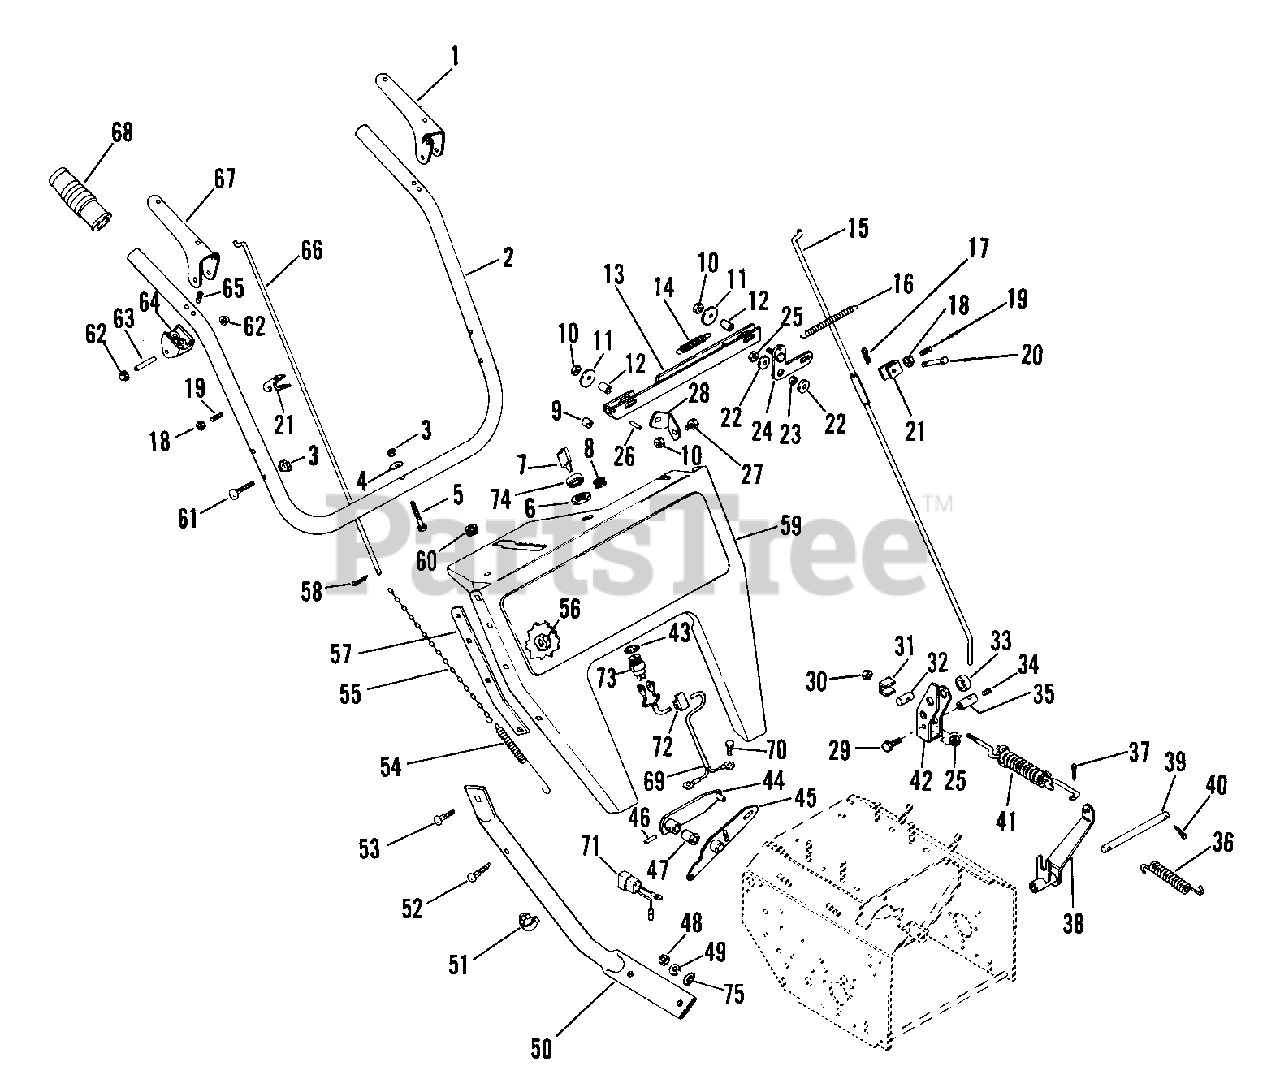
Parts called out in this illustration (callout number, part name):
1	HANDLE - TRACTOR CLUTCH
2	UPPER HANDLEBAR LW
2	UPPER HANDLEBAR
3	NUT-LK-FLG .250-20 PL
4	WSHR-FL-STL .265X.500X.087 PL
5	BLT-HEX .25-20X1.50 PL GR5
6	NUT-PANEL .625-32 GRECO
7	KEY SET
8	SNAP BUSHING
9	BSHG-SLV .188X.500X.480
10	NUT-LK-CTR .250-20 PL
11	WSHR-FL-STL .281X1.250X.048PL
12	BSHG-SLV .250X.375X.640
13	SLIDER
14	SG-TENS .035X.45X2.75 WLD 3.5
15	CLUTCH ROD
16	SG-TENS .062X.43X5.75 WLD 20
17	PIN-HAIR INT .06X.18X.77
18	NUT-HEX JAM .25-20 YWZC
19	SCR-SET .25-20X.75 SKHCUP OH
20	CLEVIS PIN
21	CLEVIS
22	WSHR-FL-STL .328X.875X.062 PL
23	SPACER BUSHING .5 X .32 X .163
24	BELLCRANK
25	NUT-LK .312-18 GR A PL
26	PIN-ROLL .188X.88
27	BLT-HEX .25-20X.50 PL GR2
28	STUD BRACE
29	BLT-HEX .31-18X.75 PL GR2
30	NUT-LK-NYL.312-18 PL
31	ADAPTER SPACER
32	ADAPTER
33	SPACER 1.00 X .64 X .38
34	SCR-SET .32-18X.38 SKHCUPNL OH
35	ROD ADAPTER
36	SG-TENS .080X.73X3.06 WLD 20
37	PIN-COTR .09X.75 PL
38	FORK, CLUTCH
39	ROD, FORK PIVOT
40	PIN-COTR .09X1.0 PL
41	SPRING ASSEMBLY
42	CLUTCH ENGAGEMENT YOKE
43	WSHR-LK-INT .625X.045 PL
44	LEVER CLUTCH
46	PIN-ROLL .156X.88
47	BSHG-FLG.500X.625X.312X.750NY
48	NUT-HEX .375-16
49	WSHR-LK .375X.115 HVY PL
50	LOWER HANDLEBAR LH
50	LOWER HANDLEBAR RH
52	BLT-RDHDSQNK .31-18X1.50 PL BL
53	BLT-RDHDSQNK .31-18X.75 PL BL
54	SG-TENS .091X.56X6.12 WLD 40
55	CLUTCH CHAIN
56	NUT-FLG. .312-18 PL
57	L H STIFFENER
57	R H STIFFENER
58	PIN-COTR .12X.50 PL
59	PANEL W/DECAL
59	UPPER HANDLEBAR PANEL
60	SNAP BUSHING-.437
61	BLT-RDHDSQNK .25-20X1.50 PL BL
62	PUSH NUT, .25
64	HANDLE PIVOT
65	SCR-TAP 12-14X1.50 CROVH PL BT
66	ATTACH CLUTCH ROD
67	HANDLE - ATTACHMENT CLUTCH
68	GRIP
69	SHORTING WIRE
70	SCR-TAP .250-20X.37 HWH PL TR
71	JUMPER
72	WIRE CLIP
73	KEY SWITCH ASSEMBLY
74	CAP - IGNITION SWITCH
75	WSHR-FL-STL .438X1.0X.083 PL
